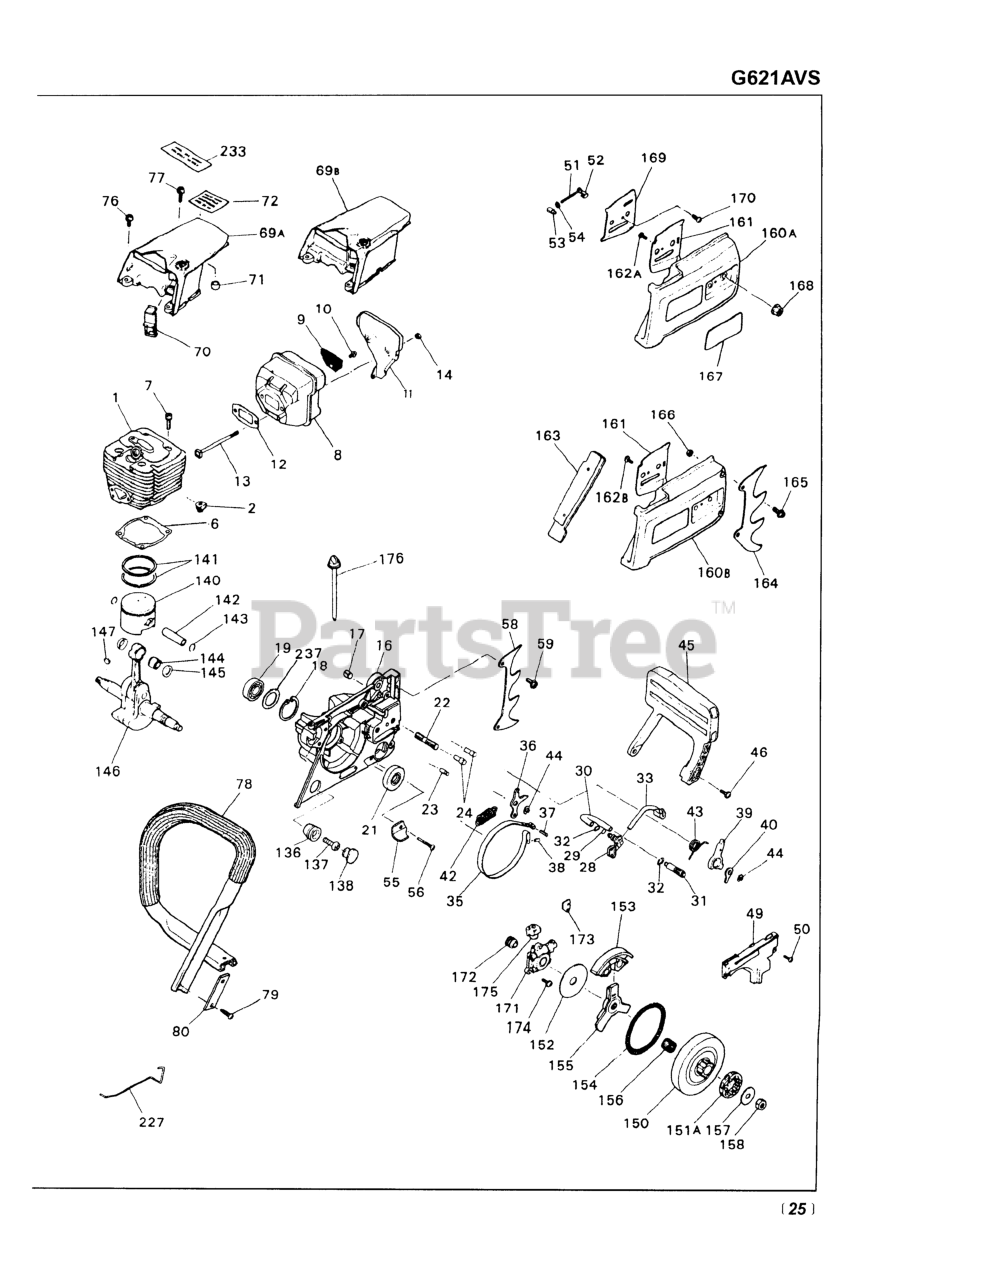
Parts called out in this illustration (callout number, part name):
2	GROMMET
6	GASKET, CYLINDER (RPLS.-14210)
7	BOLT M5 x 20 (RPLS -12280)
8	MUFFLER (REPLACES 3359-15111)
9	ARRESTER, SPARK
10	SCREW, M4 X 8
12	GASKET
13	BOLT
18	RING, SNAP, M35 X 1.5
22	STUD (RPLS 0205-50825)
23	PIN
24	PIN
28	PIPE, OIL
31	WEIGHT
33	PIPE, OIL
35	BAND
36	ARM
38	PIN
39	LEVER, BRAKE (RPLS.3356-24210)
42	SPRING COMP
43	SPRING
44	RING, SNAP, M6
49	COVER, BRAKE (RPLS -24411)
50	SCREW, M5 x 14
51	ADJUST SCREW
52	STOPPER, ADJUS
53	NUT (A)
54	WASHER, M5 X .8
55	CATCHER, CHAIN (RPLS -25210)
58	BUMPER SPIKE
59	SCREW
69B	COVER (G621AVS)
70	CAP
71	GROMMET (RPLS-31151)
76	SCREW,M5 X 14 (RPLS 1400-15510
77	SCREW, M5X20 (RPLS.1400-75510)
78	HANDLE L
79	SCREW (USE 848-825-1901)
80	PLATE (RPLS 2616-32180)
136	DAMPER (RPLS 2670-35110)
137	SCREW
138	CAP
140	PISTON
141	RING
142	PIN, PISTON
143	RING, SNAP
144	BEARING
145	WASHER (RPLS 1491-41510)
146	CRANKSHAFT (RPLS -42003)
147	KEY
150	DRUM, CLUTCH
151A	SPROCKET RIM, 3/8, 7-TOOTH
152	PLATE
154	SPRING (RPLS -51230)
156	BEARING
157	WASHER
158	NUT
160A	COVER, CHAIN (RPLS. -53002)
160B	CHAIN COVER
161	PLATE (OUT)
162A	SCREW, M4 x 10
162B	SCREW, M4 x 10
163	PROCTECTOR
164	BUMPER SPIKE
165	SCREW (REPLACES 2616-24320)
166	NUT (B)
168	NUT
169	PLATE (IN)
170	SCREW, M4 x 10
172	GEAR, WORM
173	GASKET, PUMP
174	SCREW, M5X20 (RPLS.1400-75510)
175	GROMMET (RPLS -55451)
176	SHAFT
227	ROD (RPLS 3356-82411)
237	RING
NI	OIL PIPE COMP
NI	BAND COMP
NI	COVER COMP. (RPLS-31103)
NI	R HANDLE ASSY (RPLS -33002)
NI	PIPE ASSEMBLY
NI	FILTER ASSY
NI	BREATHER ASSEMBLY
NI	SHIM (REPLACES 848-870-G000)
NI	CLUTCH ASSY (RPLS -51200)
NI	ROTOR COMP.
